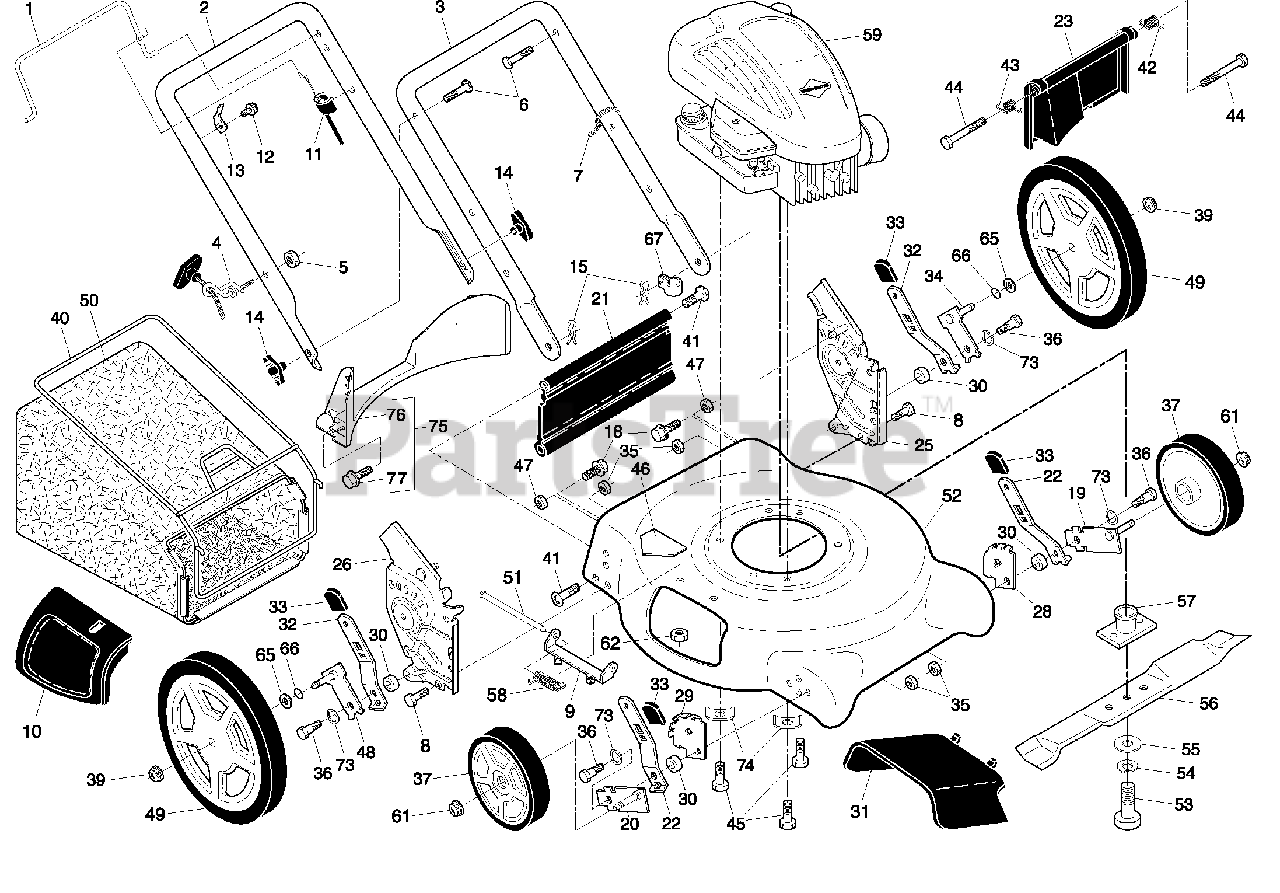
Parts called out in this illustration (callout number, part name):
1	Control Bar
2	Upper Handle
3	Lower Handle
4	Rope Guide
6	Handle Bolt
7	Wire Tie
8	Bolt
9	Hinge Bracket
10	Mulcher Door
11	Engine Zone Control Cable
12	Hex Washer Head Screw
13	Up-Stop Bracket
14	Handle Knob
15	Hairpin Cotter
18	Screw 1/4-20 x 3/8
19	Axle Arm Assembly, Front, LH
20	Axle Arm Assembly, Front, RH
21	Kit, Rear Skirt
22	Selector Spring, Front
23	Rear Door Assembly
25	Handle Bracket Assembly, LH
26	Handle Bracket Assembly, RH
28	Wheel Adjusting Bracket, Front, LH
29	Wheel Adjusting Bracket, Front, RH
30	Spacer
31	Discharge Deflector
32	Selector Spring, Rear
33	Selector Knob
34	Axle Arm Assembly, Rear, LH
35	Locknut, Hex 5/16-18
36	Shoulder Bolt 5/16-18
37	Wheel & Tire Assembly, Front, 7"
39	Locknut, Hex, Flanged
40	Frame, Grass Bag
41	Hinge Screw
42	Spring, Rear Door, LH
43	Spring, Rear Door, RH
44	Bolt, Rear Skirt
45	Hex Head Thread Rolling Screw 3/8-16 x 1
46	Danger Decal
47	Nut, Hex
48	Axle Arm Assembly, Rear, RH
49	Wheel & Tire Assembly, Rear, 12"
50	Grass Bag
51	Rod, Hinge
52	Housing Assembly
53	Hex Head Screw 3/8-24 x 1-3/8 Grade 8
54	Helical Lockwasher
55	Hardened Washer
56	21" Blade
57	Blade Adapter
58	Spring, Hinge
61	Locknut, Hex, Flanged
62	Locknut, Hex 1/4-20
65	Washer, Flat
66	O-Ring
67	Clip, Cable
73	Washer, Curved
74	Washer, Special, Engine
75	Kit, Rear Baffle
76	Baffl e, Rear
77	Screw, Rear Baffle
77	Operator's Manual, English
77	Operator's Manual, Spanish
77	Repair Parts Manual
